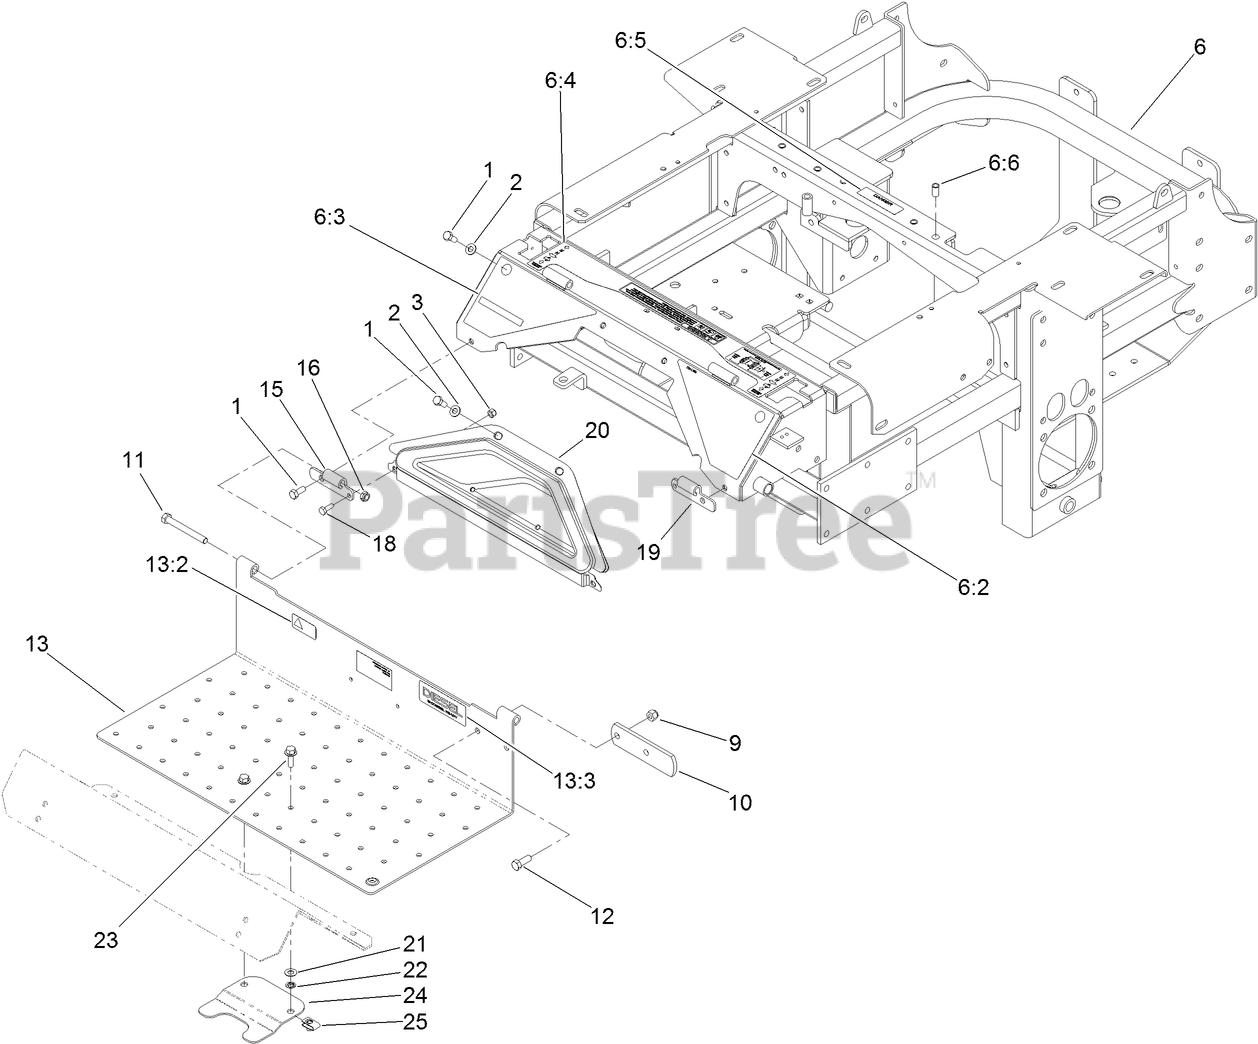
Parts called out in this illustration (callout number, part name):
1	SCREW-HH
2	WASHER-FLAT
3	NUT-LOCK, NI
6	TRACTION FRAME ASM
6:2	DECAL-DANGER, LEFT
6:3	DECAL-WARNING, RIGHT
6:4	DECAL-CONSOLE, TOP (CE)
6:5	DECAL-WARNING
6:6	INSERT-THREADED
9	NUT-LOCK, NI
10	STOP-BRAKE, PARK
11	SCREW-HH
12	SCREW-HH
13	FLOOR PAN ASM
13:2	DECAL-PROTECTION, EAR
13:3	DECAL-DIESEL, BIO-READY
15	Hinge-Floorpan, LH
16	NUT-LOCK, NI
18	SCREW-HH
19	Hinge-Floorpan, RH
20	Pocket
21	WASHER-THRUST
22	NUT-PUSH
23	SCREW-HHF
24	ADAPTER-CAPTIVE
25	NUT-U
